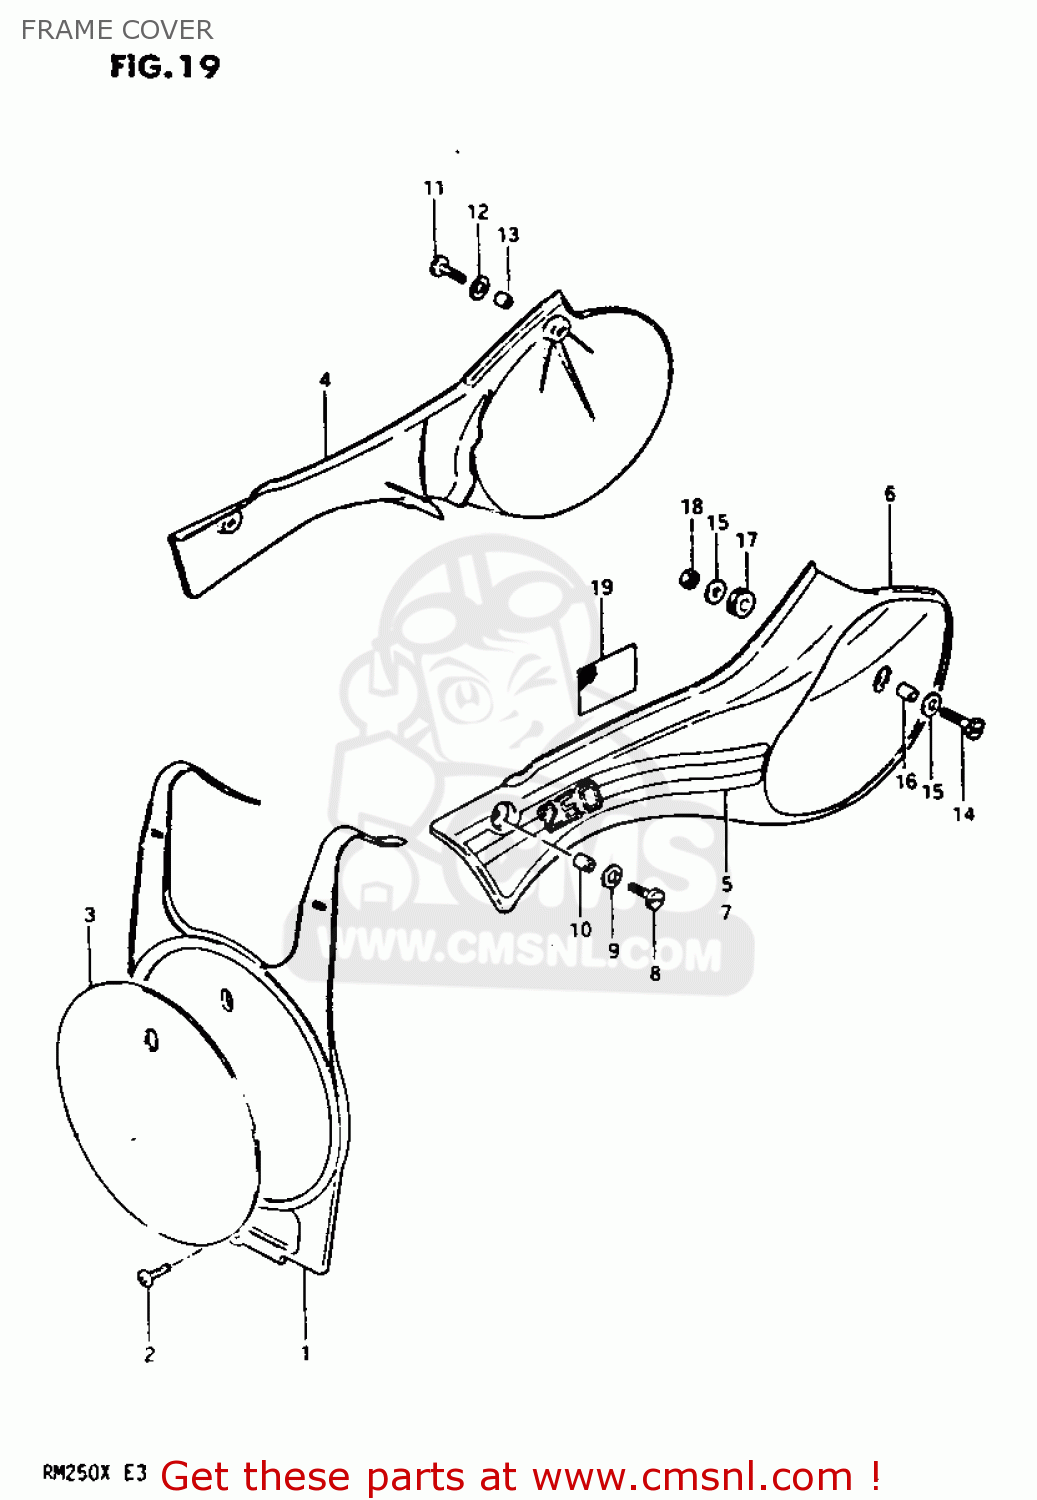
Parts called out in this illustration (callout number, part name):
1	PLATE,NUMBER,FRONT
2	(5X20) CROSS SCREW
3	EMBLEM,FRONT NUMBER PLATE
4	COVER,FRAME,R(YELLOW)
5	TAPE,FRAME COVER
6	COVER,FRAME,LEFT
7	TAPE,FRAME COVER
8	SCREW(6X25)
9	WASHER FRAME COVER
10	SPACER,FRAME COVER,FRONT
11	SCREW
12	WASHER FRAME COVER
13	SPACER FRAME COV RR
14	SCREW(6X25)
15	WASHER FRAME COVER
16	SPACER,FRAME COVER,FRONT
17	CUSHION
18	NUT 6MM
19	HEAT SHIELD,FRAME COVER
